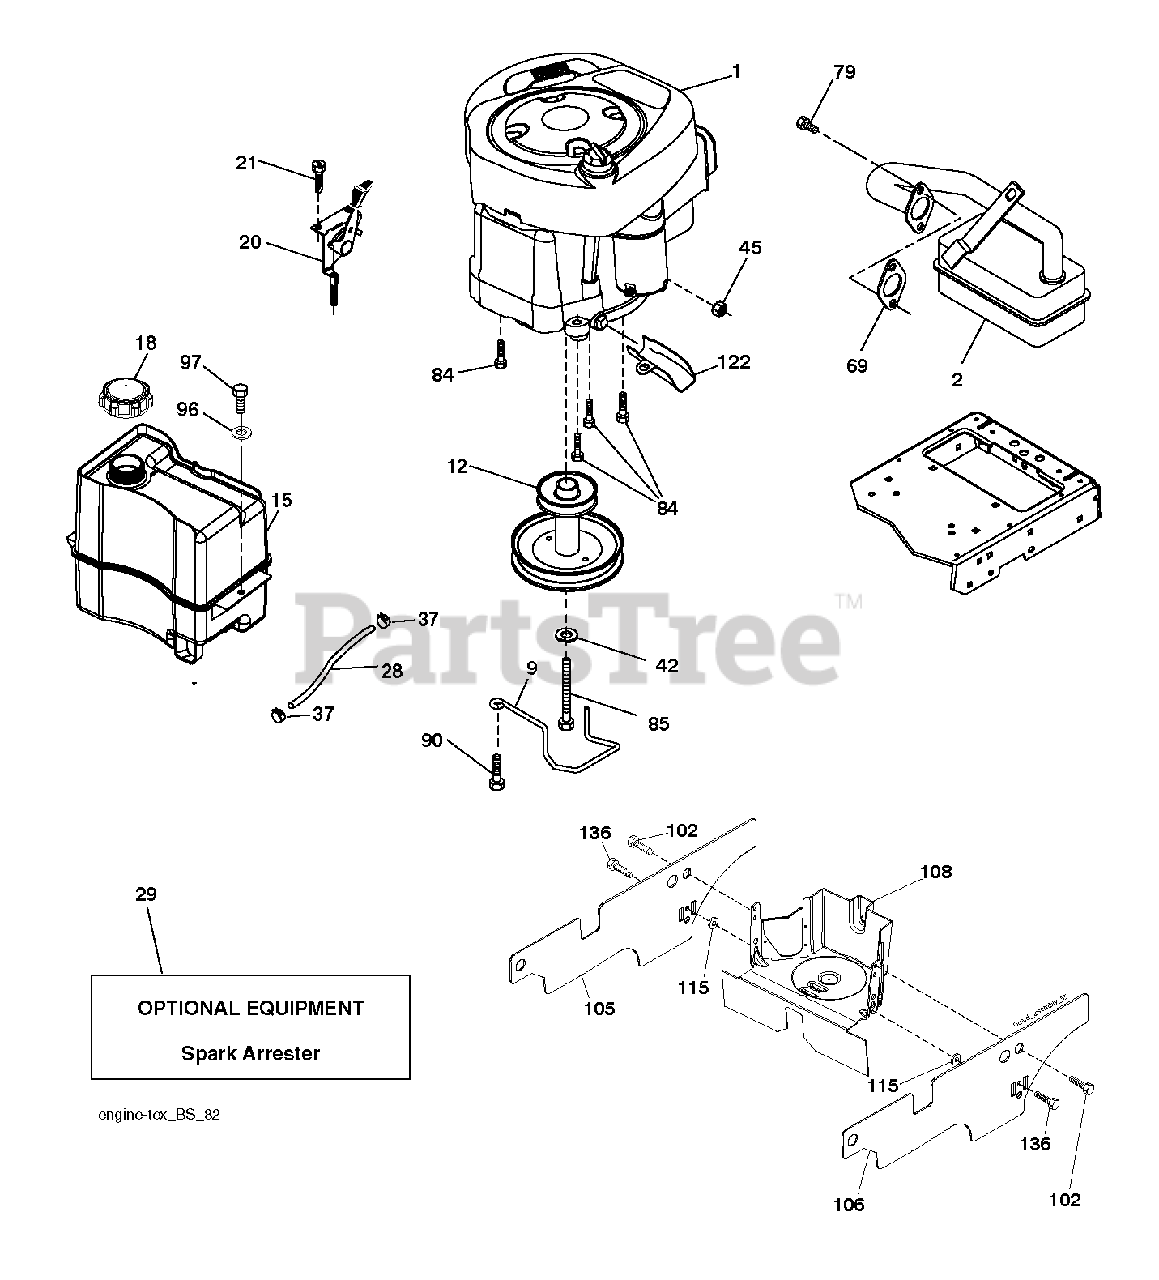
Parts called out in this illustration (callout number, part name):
2	MUFFLER.B&S.MODEL.21.11HP.OHV
9	KEEPER.BELT.ENGINE
12	PULLEY.ENGINE
15	RP TANK FUEL FRT 1.5 GAL
18	CAP ASM.FUEL.2.25"FR.
20	CONTROL.TH/CK.C.
21	SCREW.#10 X 0.750.BOS
28	LINE.FUEL.20
29	KIT.SPARK ARRESTOR 794945 B&S
37	HOSE CLAMP
42	LOCKWASHER
45	NUT
69	GASKET.EXHAUST.KOHLER
79	SCREW.SOCKET HD.5/16-1
84	SCREW.3/8-16
85	BOLT HEX 7/16-20X4-1/4"
90	SCREW 3/8-16X1
97	SCREW HEXWSHR 1/4-20X3/4
102	SCREW
105	SHIELD.SIDE.LH.3842"TEX FRENCH
106	SHIELD.SIDE.RH.3842"TEX FRENCH
108	ENGINE COVER
115	PALNUT 1/4
122	EXTENSION DRAIN OIL
136	SCREW.1/4-20X5/8
